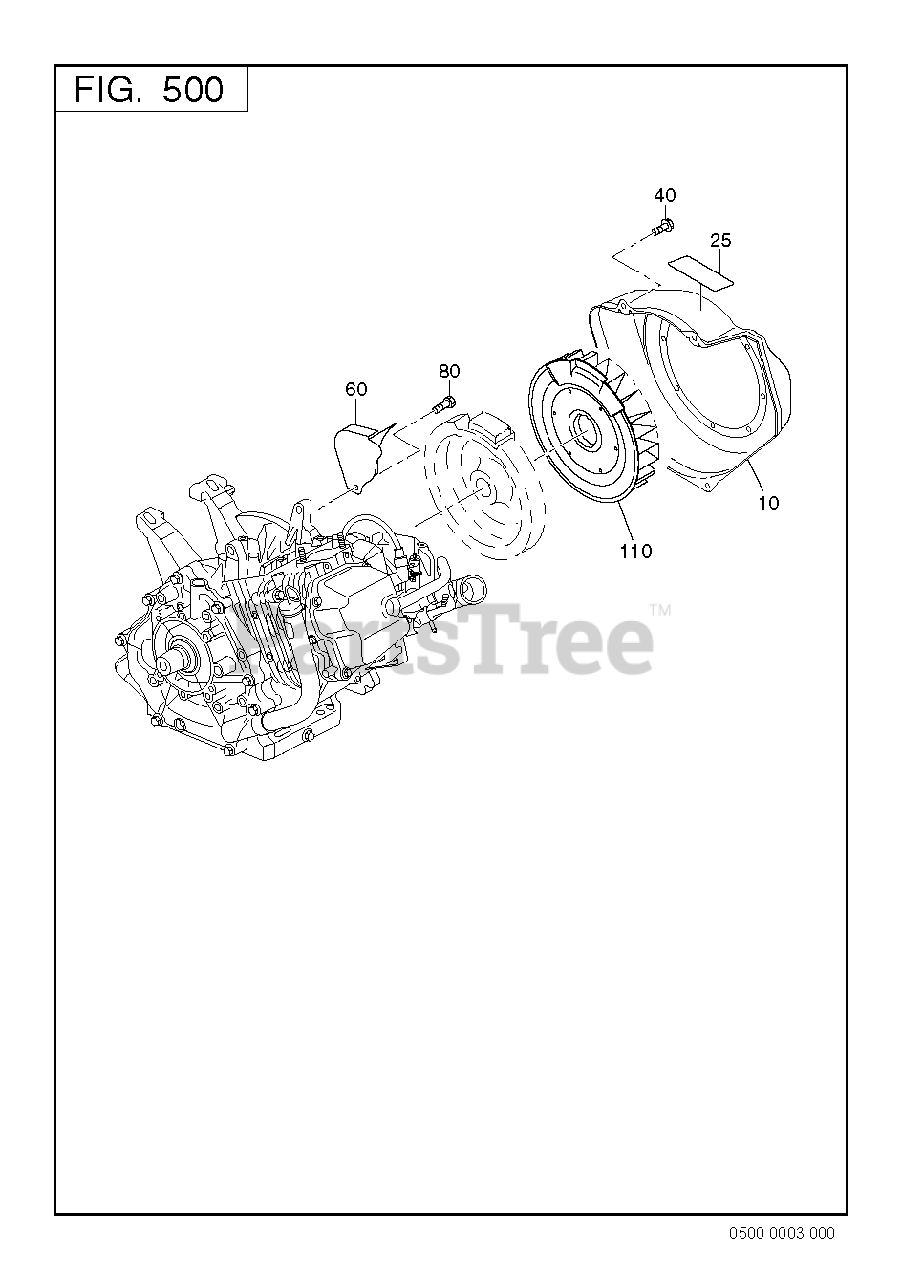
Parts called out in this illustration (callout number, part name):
10	BLOWER HOUSING CP
25	LABEL(WARNING)
60	BAFFLE 1(CASE) CP
110	COOLING BLOWER
